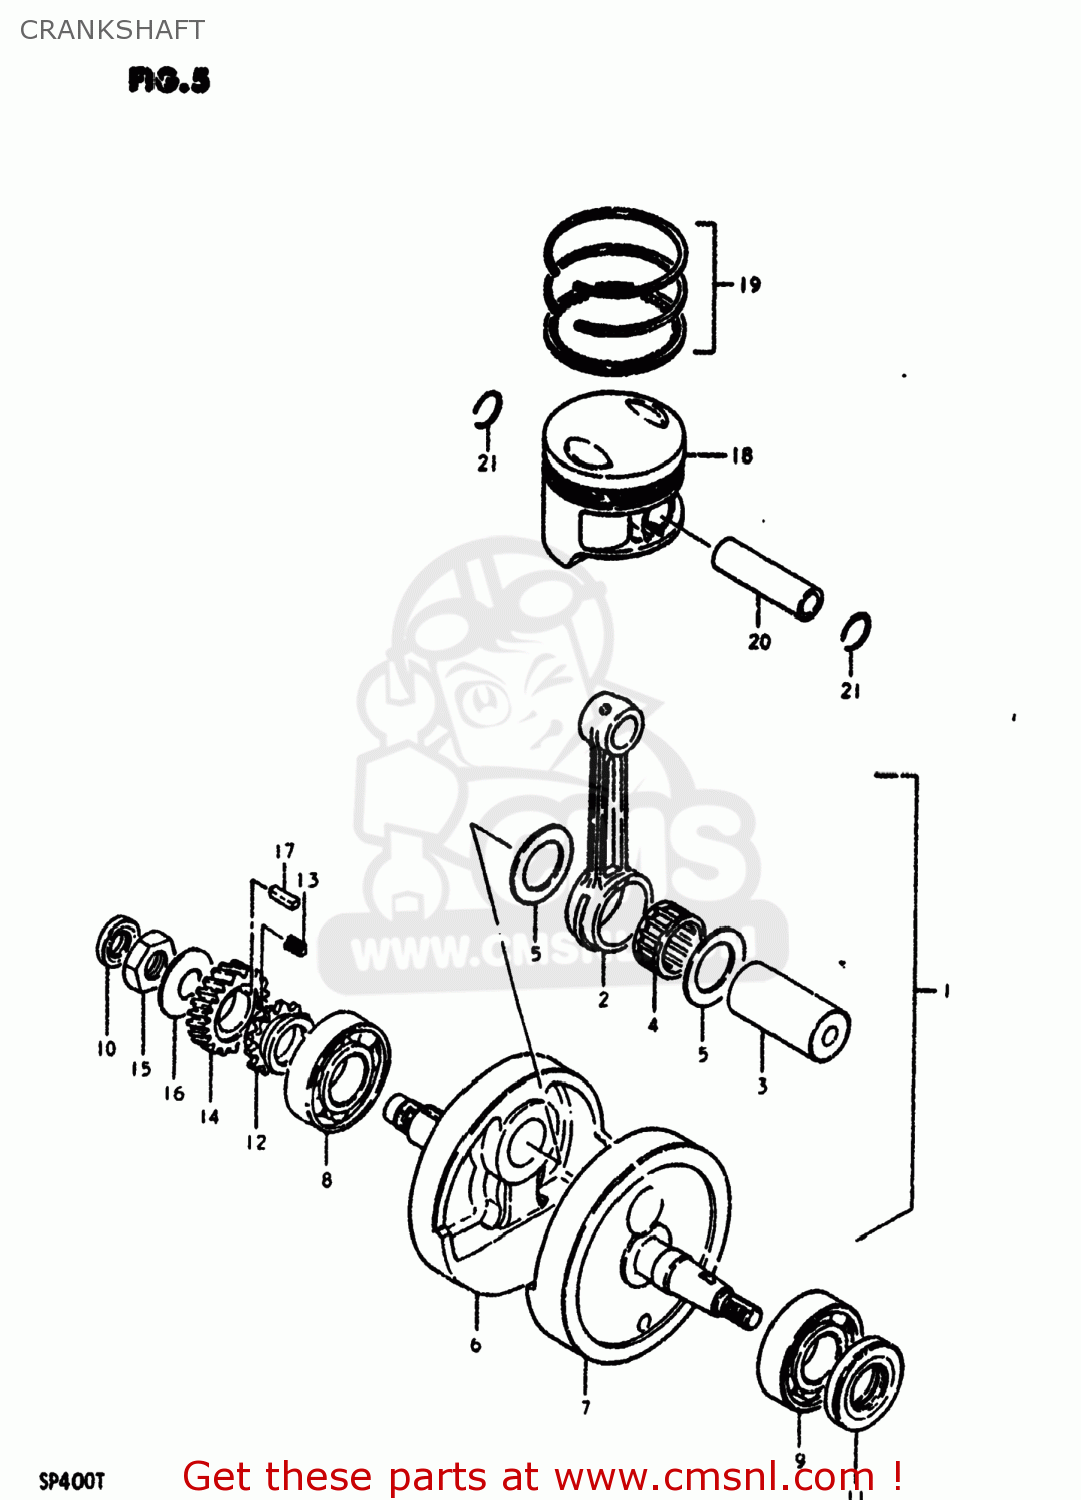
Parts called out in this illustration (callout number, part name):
1	CRANKSHAFT ASSEMBLY
2	ROD,CONNECTING
3	PIN,CRANK
4	BEARING
5	WASHER(34X52X1)
6	CRANKSHAFT
7	CRANKSHAFT,LEFT
8	BALL BEARING 30X72X19
9	BALL BEARING 30X72X19
10	SEAL,OIL(16X30X6)
11	SEAL,OIL(30X58X7)
12	SPROCKET,CAM CHAIN DRIVE
13	KEY,SPROCKET
14	GEAR,PRIMARY DRIVE
15	NUT (20MM)
16	WASHER
17	KEY
18	PISTON
19	RING SET,PISTON
20	PIN,PISTON
21	CIRCLIP
